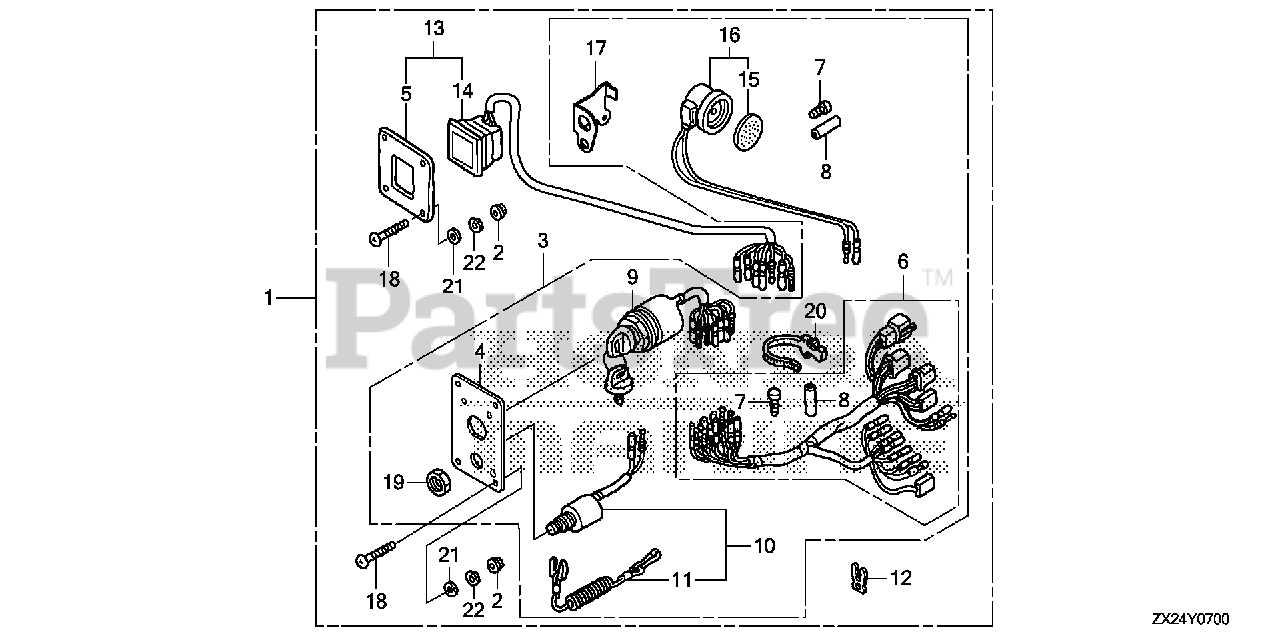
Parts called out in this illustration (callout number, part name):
1	PANEL KIT, SWITCH (4-LED) (B)
2	NUT, FLANGE (5MM)
3	PANEL ASSY., SWITCH
4	PANEL, CONTROL
5	PANEL, CONTROL
6	HARNESS ASSY., SWITCH PANEL
7	PLUG, CONNECTOR (INNER)
8	PLUG, CONNECTOR (OUTER)
9	SWITCH ASSY., COMBINATION
10	SWITCH ASSY., EMERGENCY STOP
11	WIRE, EMERGENCY
12	CLIP, EMERGENCY LOCK
13	PANEL ASSY., INDICATOR (4-LED)
14	LAMP ASSY., INDICATION (4-LED)
15	PLATE, TURN SIGNAL BUZZER
16	BUZZER, WARNING
17	BRACKET, BUZZER
18	SCREW, PAN (5X40)
19	NUT, HEX. (16MM)
20	BAND, WIRE HARNESS (150MM) (NATURAL)
21	WASHER, PLAIN (5MM)
22	WASHER, SPRING (5MM)
